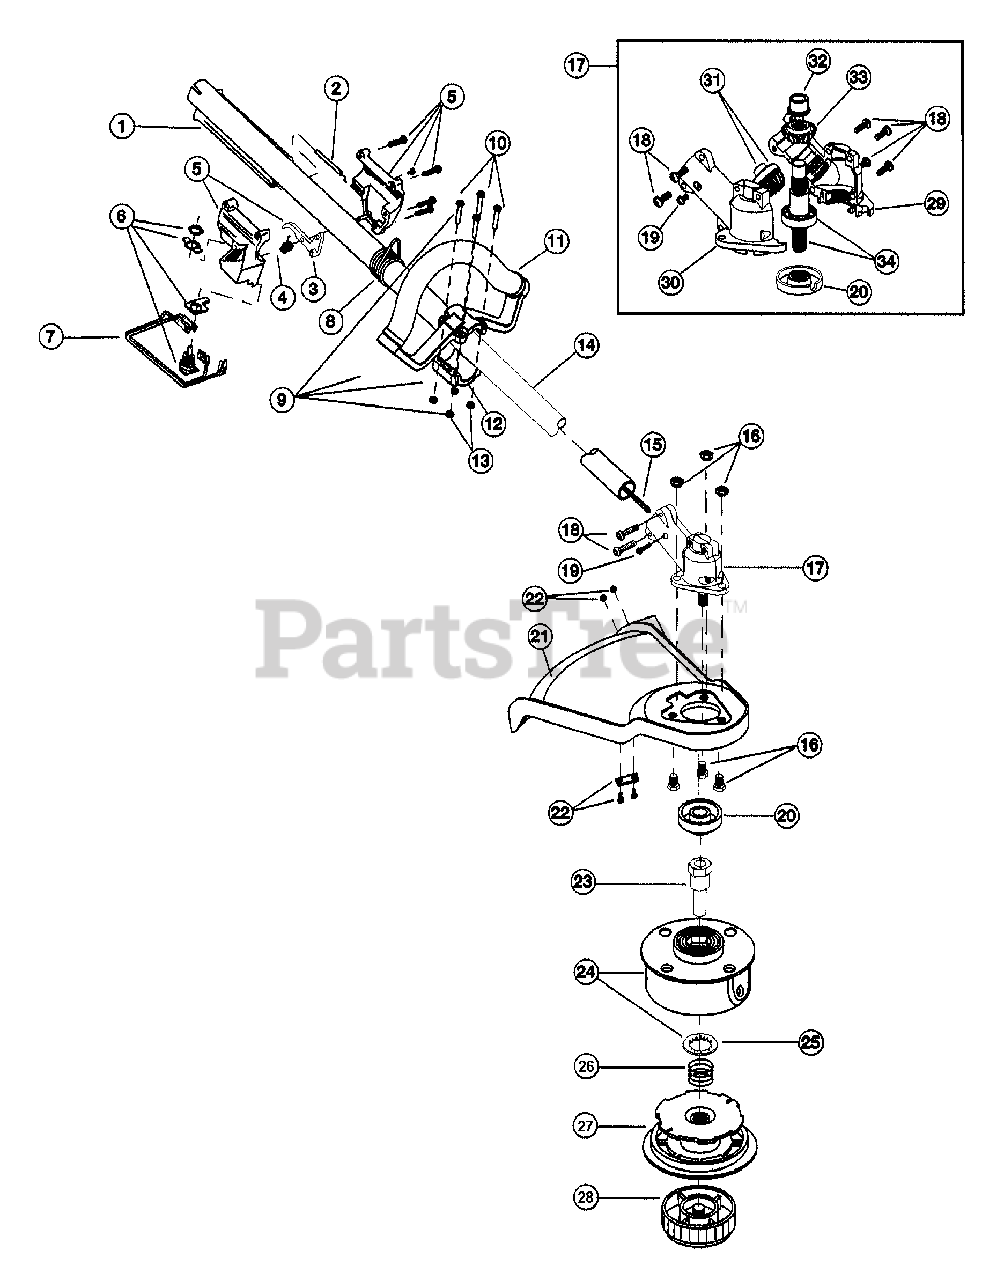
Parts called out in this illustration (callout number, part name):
2	Throttle Cable Assembly
3	Throttle Trigger
4	Throttle Trigger Spring
5	Throttle Trigger Assembly
6	Switch Assembly
7	Wire Lead Assembly
8	Shoulder Harness Clamp
9	Loop Handle Assembly
11	Loop Handle
12	Bottom Clamp
14	Drive Shaft Housing Assembly
15	Drive Shaft
16	Shield Mount Screw Assembly
17	2 piece Gearbox Assembly
18	Gearbox Mounting Hardware
19	Anti-Rotation Screw
20	Blade Driver
21	Shield and Blade Assembly
22	Blade Assembly
23	Spool Shaft
24	Outer Spool & Eyelet Assembly
25	Retainer
28	Bump Head Knob Assembly
29	Left Housing
30	Right Housing
31	Pinion Gear Assembly
32	Output Shaft Bushing
33	Output Shaft Gear
34	Output Shaft Assembly
